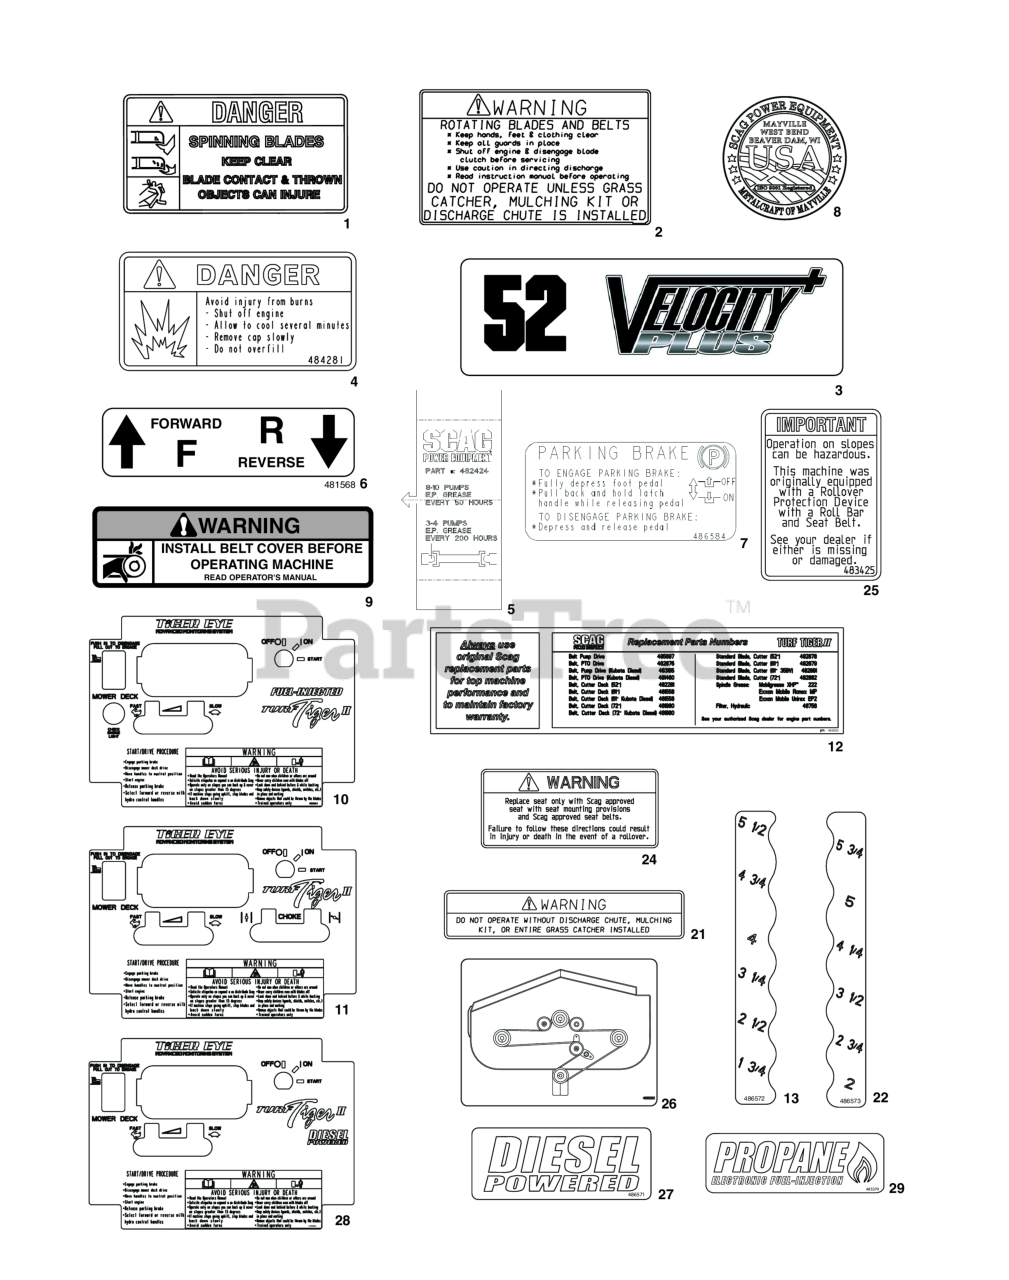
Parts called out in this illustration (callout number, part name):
1	Decal, Danger-Spinning Blades
2	Decal, Warning - Rotating Blades
3	Decal 52V 483201 Decal 61V
4	Decal, Fuel Tank - Gasoline Engines
5	Decal, Driveshaft
6	Decal, Traction Control
7	Decal, Parking Brake
8	Decal, Metalcraft - USA
9	Decal, Warning - Belt Cover
10	Decal, Instrument Panel - Fuel Injected
11	Decal, Instrument Panel
12	Decal, STTII Replacement Parts
13	Decal, Cutting Height - LH
21	Decal, Warning-Discharge
22	Decal, Cutting Height - RH
24	Decal, Seat Replacement
25	Decal, ROPS
26	DECAL, BELT ROUTING - SMT-52V/61V
27	Decal, Diesel Powered - Kubota Diesel
28	Decal, Instrument Panel - Kubota Diesel
29	Decal, Propane - Kohler LP-EFI
